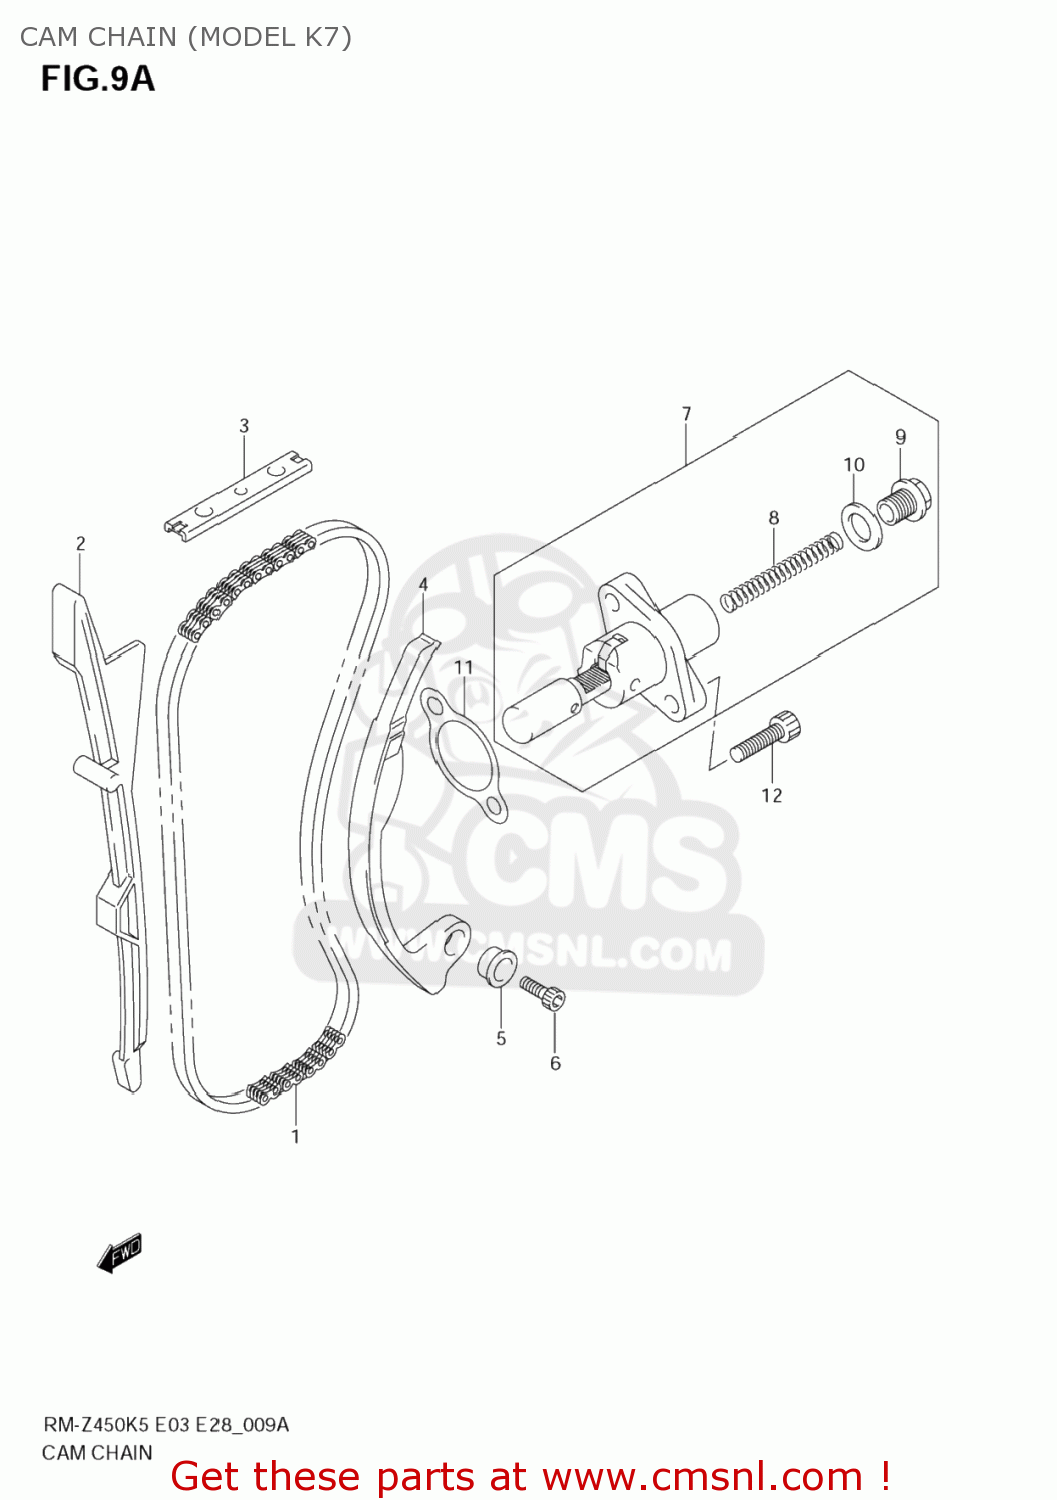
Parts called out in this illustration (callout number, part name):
1	CHAIN,CAMSHAFT DRIVE
2	GUIDE,CAM CHAIN NO.1
3	GUIDE,CAM CHAIN NO.2
4	TENSIONER,CAM CHAIN
5	SPACER,CAM CHAIN TENSIONER
6	BOLT,OIL FILLE
7	ADJUSTER ASSY,TENSIONER
8	SPRING
9	PLUG,FR TENSIONER ADJ
10	GASKET,TENSIONER ADJUSTER (NAS)
11	GASKET,TENSIONER ADJUSTER (NAS)
12	BOLT,CL.COVER
